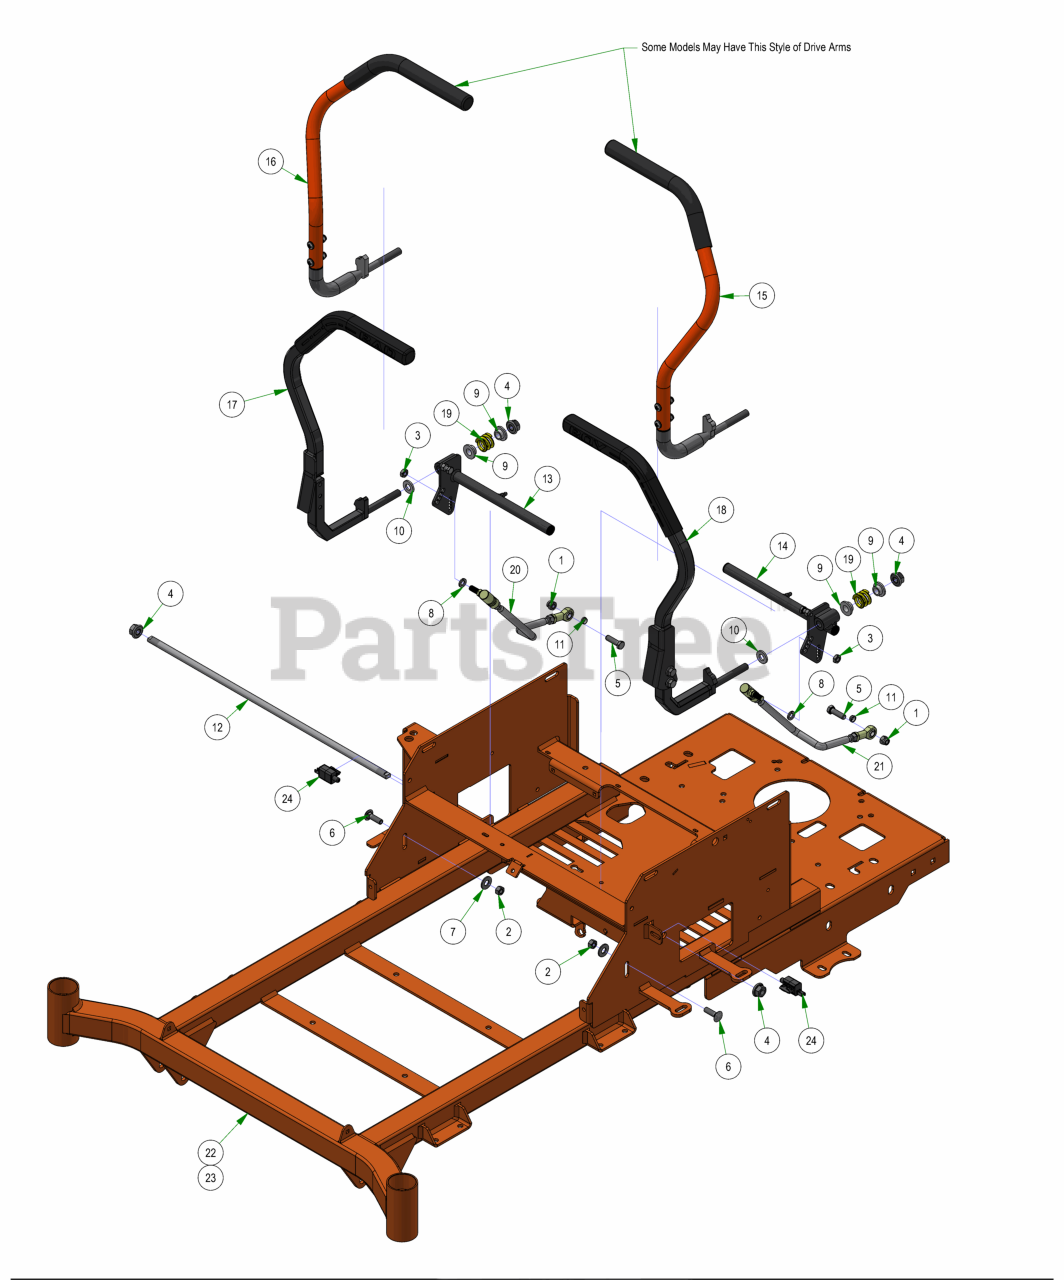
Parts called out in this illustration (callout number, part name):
1	3/8-16 NYLON INSERT LOCKNUT ZINC
2	3/8-16 HEX NUT ZINC
3	3/8-24 HEX NUT ZINC YELLOW
4	1/2-13 NYLON INSERT FLANGE LOCKNUT ZINC
5	3/8-16 X 1-1/4 HEX CAP SCREW (GR.5) ZINC
6	3/8-16 X 1-1/4 CARRIAGE BOLT ZINC
7	3/8 FLAT WASHER USS (1" OD) ZINC
8	3/8 SPLIT LOCKWASHER ZINC
9	.525 ID SHOULDER WASHER NYLON
10	.505 ID X 1.000 OD X .125 THICK FLAT WASHER NYLON
11	Drive Arm Transaxle Spacer
12	2021 Maverick Steering Actuator Rod
13	2021 Maverick Drive Arm Actuator RH Assembly
14	2021 Maverick Drive Arm Actuator LH Assembly
15	ZT Steering Arm-Left
16	ZT Steering Arm-Right
17	Small Mower Square Drive Arm RH Assembly
18	Small Mower Square Drive Arm LH Assembly
19	Drive Lever Spring
20	Push Rod-Right
21	Push Rod-Left
22	2025 MZ 42-48 Frame
23	2025 MZ-Avenger 54-60 Frame
24	Rail Mount Safety Switch
